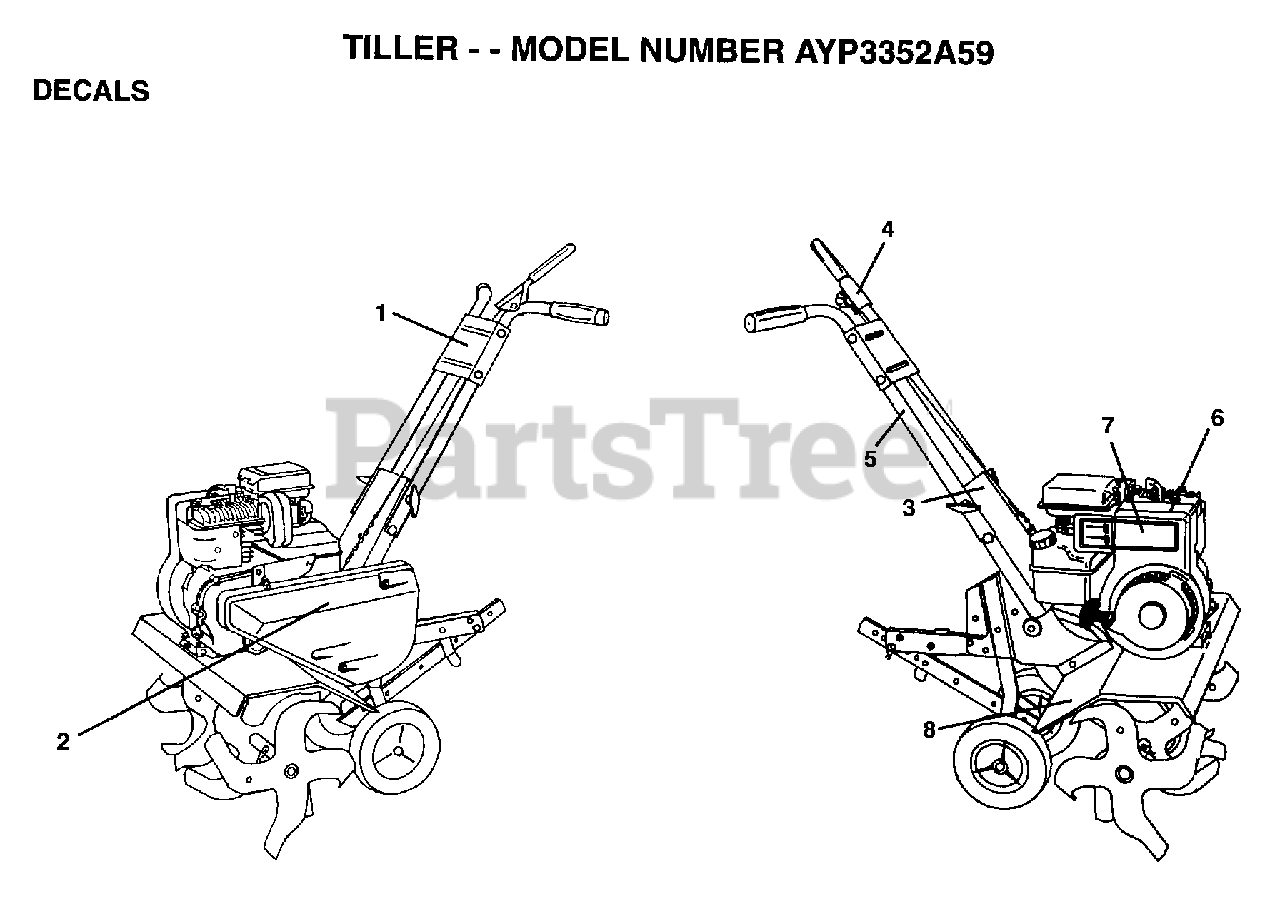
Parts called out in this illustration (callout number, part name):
1	DECAL.CNTRL.PNL.5
2	DECAL.GUARD.BELT.
4	DECAL TI
5	DECAL TI
7	DECAL, BRIGGS & STRATTON
8	DECAL TI
